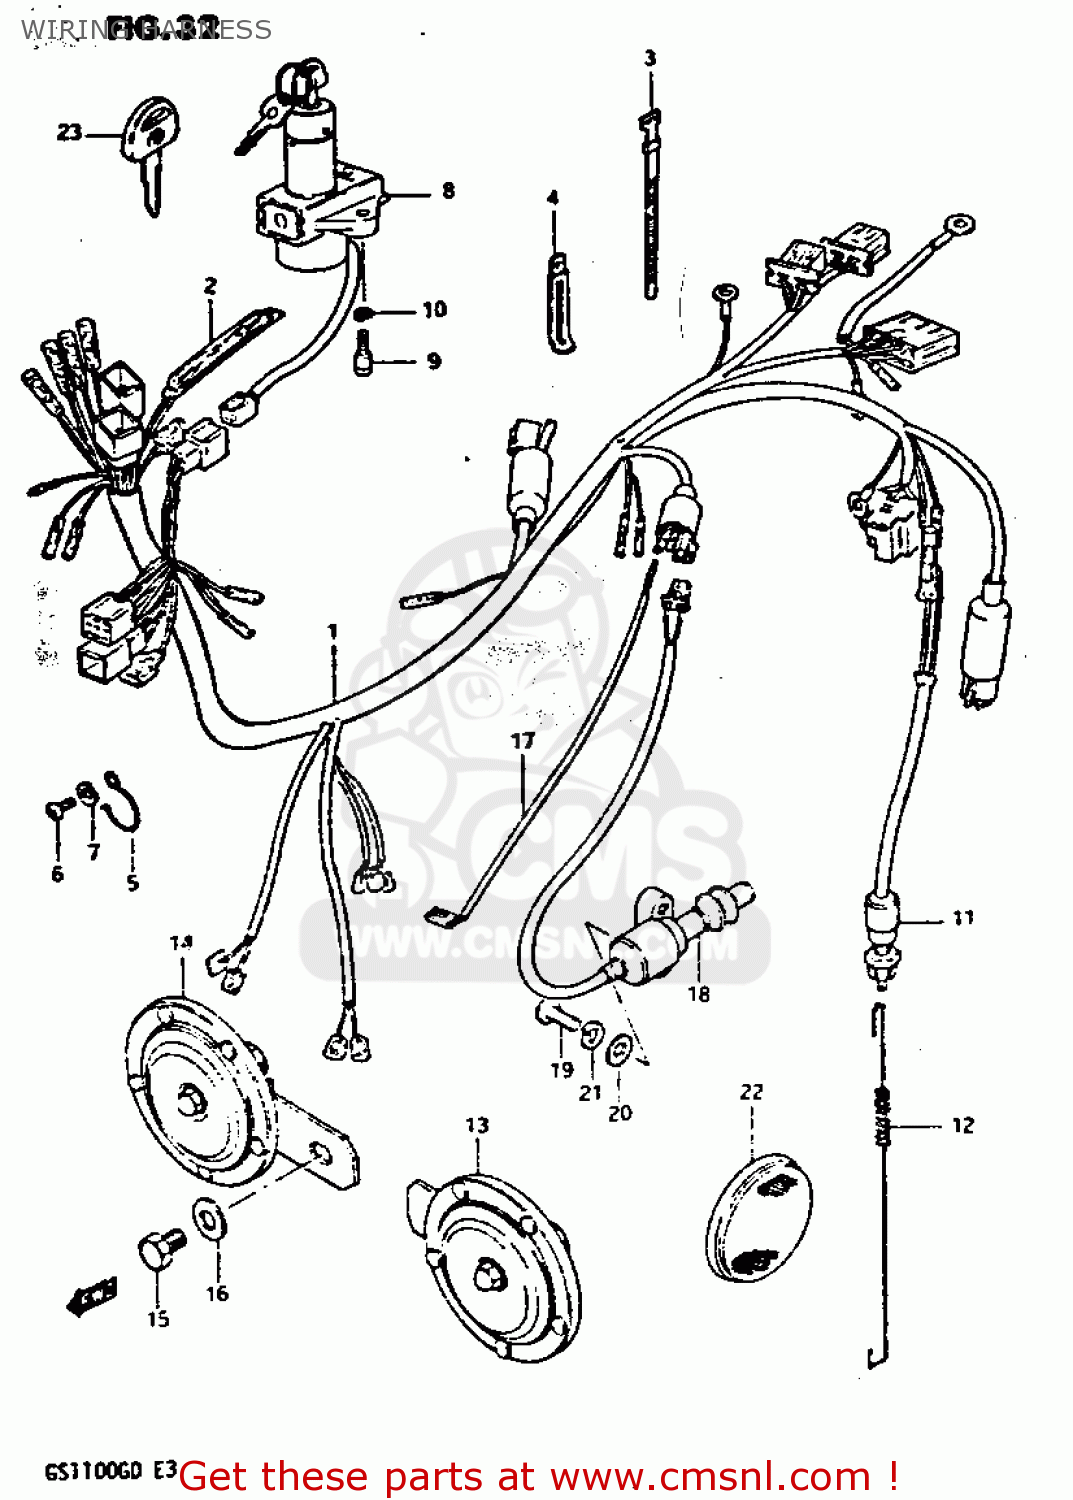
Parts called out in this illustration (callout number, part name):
1	HARNESS,WIRING
2	DIODE
3	CLAMP(L:120)
4	CLAMP
5	CLIP,WIRING HARNESS
6	SCREW 6X12
7	WASHER
8	SWITCH ASSY,IGNITION
9	BOLT
10	WASHER,LOCK
11	SWITCH ASSY,STOP LAMP
12	SPRING
13	HORN ASSEMBLY,LOW PITCH
14	HORN ASSEMBLY,HIGH PITCH
15	BOLT
16	WASHER
17	WIRE,OIL PRESSURE SWITCH LEAD
18	SWITCH ASSY,SIDE STAND WARN
19	BOLT
20	WASHER
21	LOCK WASHER
22	REFLEX REFLECTOR,RR
23	KEY,BLANK
